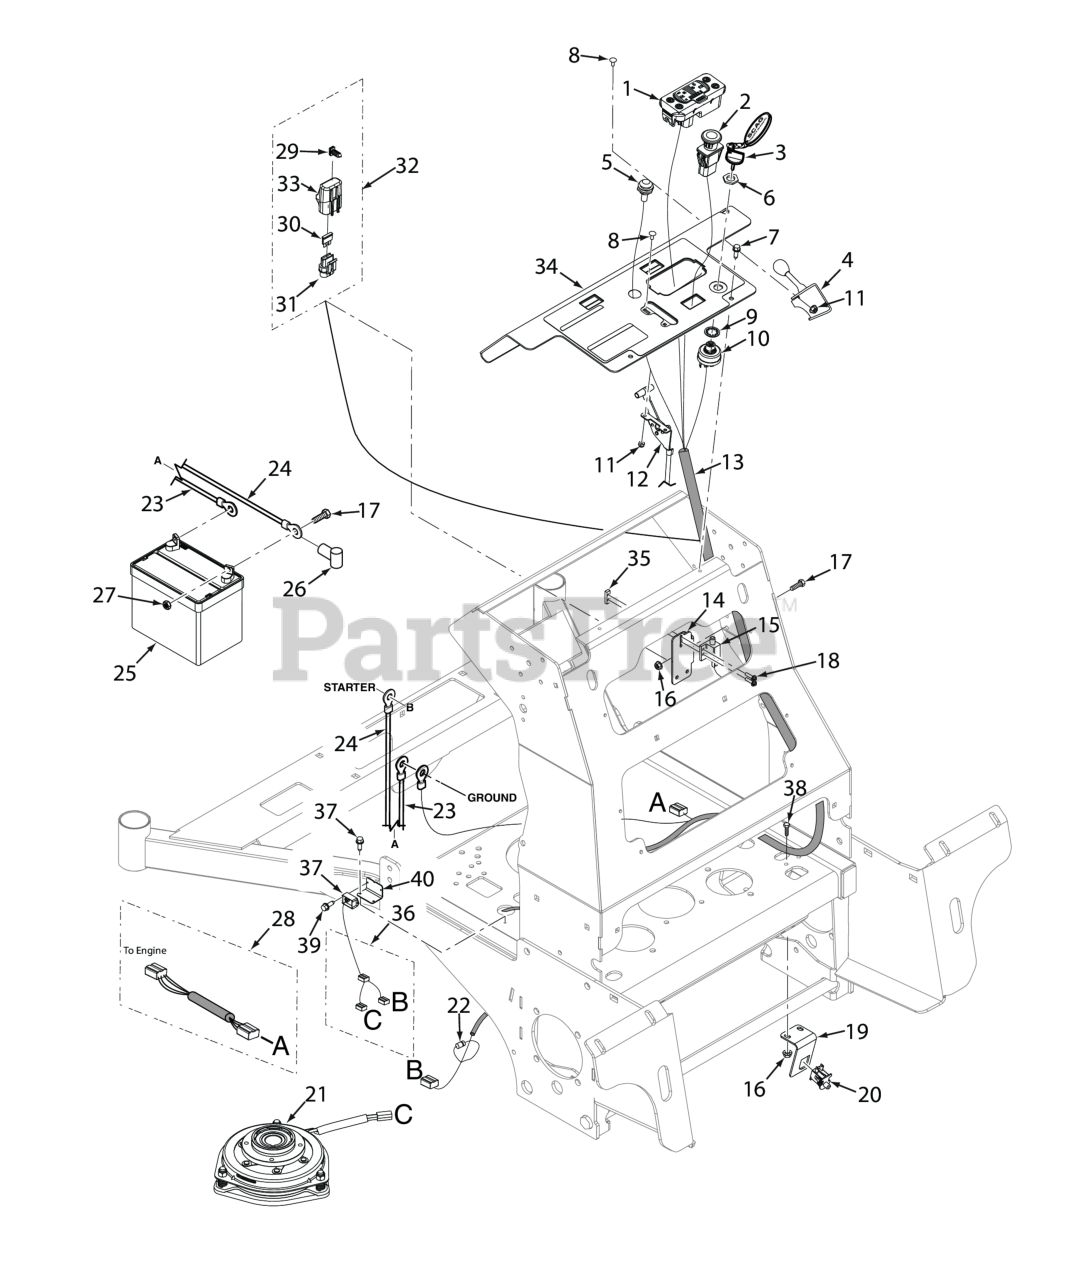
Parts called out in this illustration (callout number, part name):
1	Tiger Eye, Cluster Gauge
2	Switch, PTO - 10 Amp
3	Key, Assembly w/Fob
4	Control Cable, Air Direction
5	Indicator Light, Glow Plugs (Includes Mounting Hardware)
6	Nut, 5/8-32 Special
7	Screw, Self-Tapping 1/4-20 x 3/4
8	Bolt, Carriage #10-24 x 1/2"
9	LOCK WASHER, 5/8" INTERNAL TOOTH
10	KEY SWITCH(INCLUDES MOUNTING HARDWARE)
11	Nut, Elastic Stop #10-24
12	Throttle Control, SVR
13	Wire Harness, SVRII-EFI
14	Bracket, Neutral Switch
15	Switch, Interlock, Park Brake Normally Open
16	NUT, 1/4-20 SERRATED FLANGE HEX HEAD
17	BOLT, HEX HEAD, 1/4-20 X 3/4 GR.5
18	Screw, Hex-Slotted Washer Head #10 32 x 3/4"
19	Mounting Bracket, Footplate Switch
20	SWITCH, NEUTRAL INTERLOCK
21	Clutch, GT3.5 (28.6mm Bore)
22	Diode, 600V 6 Amp
23	Battery Cable, 39" Black (26EFI) - Kohler
24	Battery Cable, 44" Red w/Braid (26EFI) - Kohler
25	Battery, 350 CCA (not available through Scag)
26	RUBBER BOOT
27	Nut, 1/4 - 20 Hex
28	Wire Harness Adapter, Briggs & Stratton 37 BV-EFI
29	Clip, Fuse Holder
30	FUSE, 20 AMP BLADE TYPE AUTOMOTIVE
31	Fuse Holder Assembly
32	Single Fuse Assy., Excluding Fuse
33	Cover, Sealed Single
34	Control Panel w/Decals
35	Plate, Threaded
36	Wire Harness, Clutch Soft Start
37	Soft Start Module, Clutch
38	Serr. Fl. Hex Head CPSCR, 1/4-20 x 3/4"
39	Screw, #10-32 x .563 Shakeproof
40	Mounting Bracket, Soft Start Module
